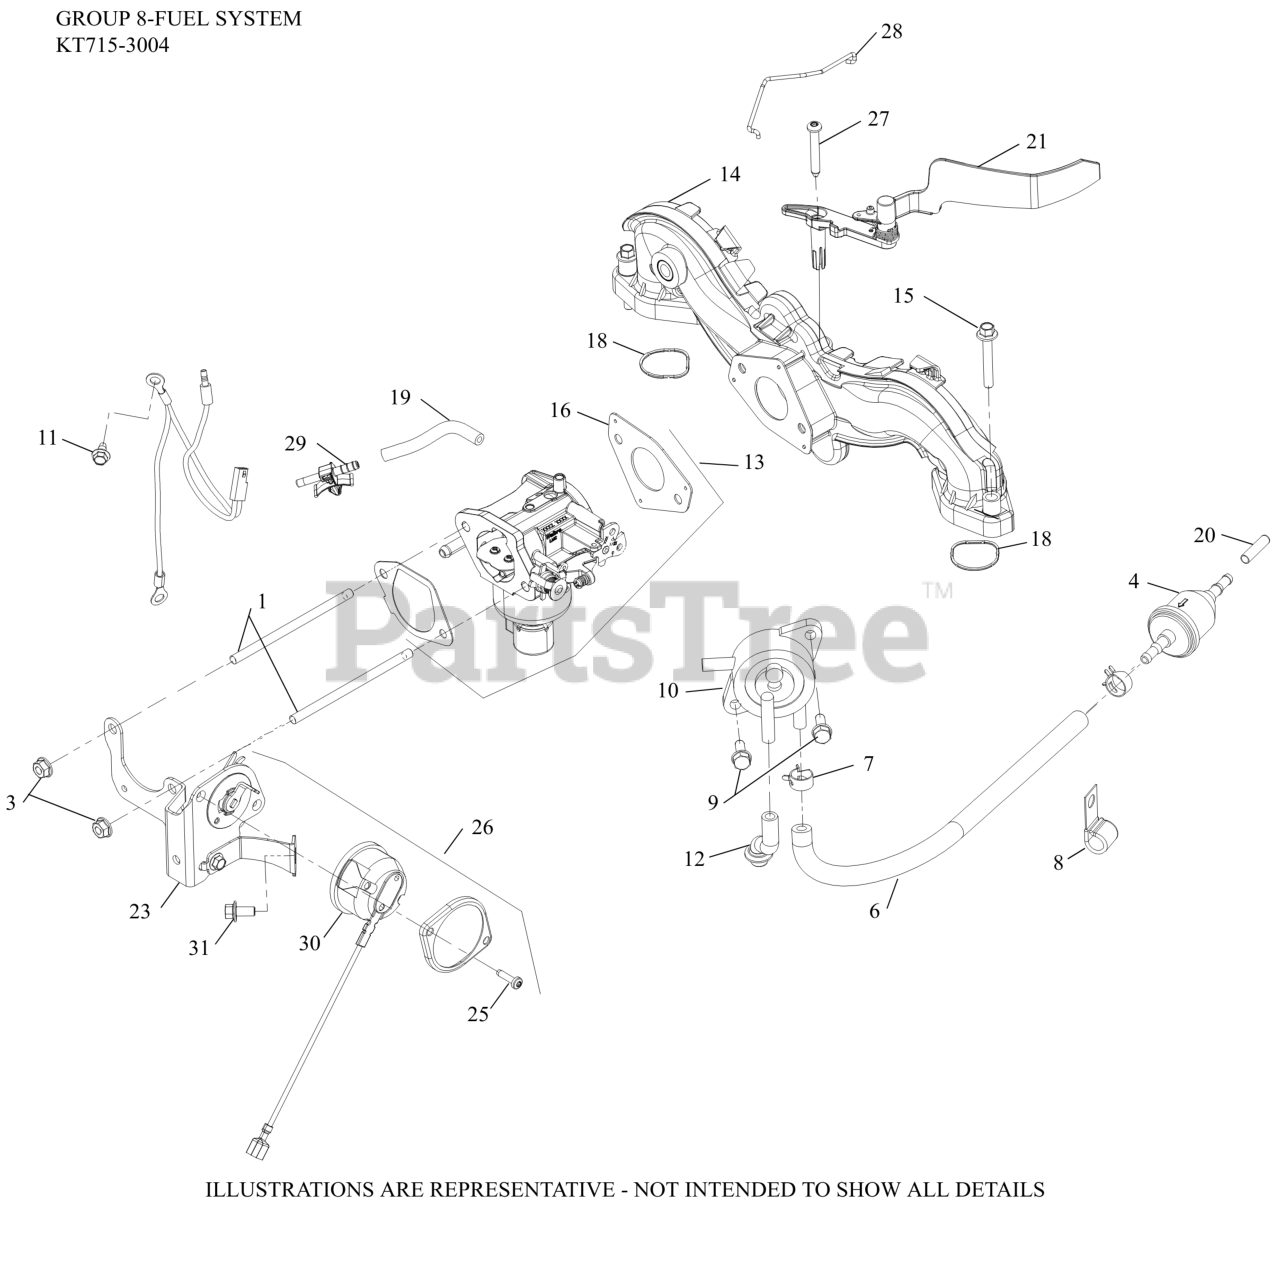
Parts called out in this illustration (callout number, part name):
3	NUT, FLG M6X1.0
4	FILTER,FUEL 51 MICRON (FUEL PUMP)
6	HOSE,LW PERM.FUEL 24.00"-USE 25 111 81-S
7	SPRING CLAMP, HOSE
8	CLIP, CABLE
9	SCREW, TAP M6X1.7X18
10	PUMP, FUEL (PULSE)-(#2539326S)
11	SCREW, THREAD FORMING
12	HOSE, PULSE PUMP(STEEL COVERS)
13	KIT,CARB(WALBRO)
14	KIT, INTAKE MANIFOLD-(#24164277S)
15	SCREW, FLG M6X1.0X40
16	GASKET, CARBURETOR
17	PLUG, CTSK PIPE 1/8"
18	O-RING, INTAKE PORT (PIM)
19	HOSE EVAPORATIVE (WALBRO)
20	CAP, MASKING
21	DEFLECTOR ASSEMBLY, AIR VANE
23	BRACKET ASSY, AUTO-CHOKE (MECH)
25	SCREW, PAN HEAD THREAD FORMING (M4)
26	THERMOSTAT ASSY (CDI) - USE 32 755 27-S
26	THERMOSTAT ASSY(MDI IGN)-USE 32 755 27-S
27	SCREW, PAN HEAD (#12-14 X 38 MM)
28	LINKAGE, CHOKE UPLOADER
29	CONNECTOR, EVAPORATIVE
31	SCREW, FLG M6X1.0X12
NI	KIT,REPAIR OVERHAUL(WALBRO)
NI	KIT,BOWL O-RING(WALBRO)
NI	KIT, HI ALTITUDE (5000 FT) 22MM
NI	KIT, CHOKE REPAIR (WALBRO)
NI	KIT, SOLENOID REPAIR
NI	KIT, FLOAT REPAIR
